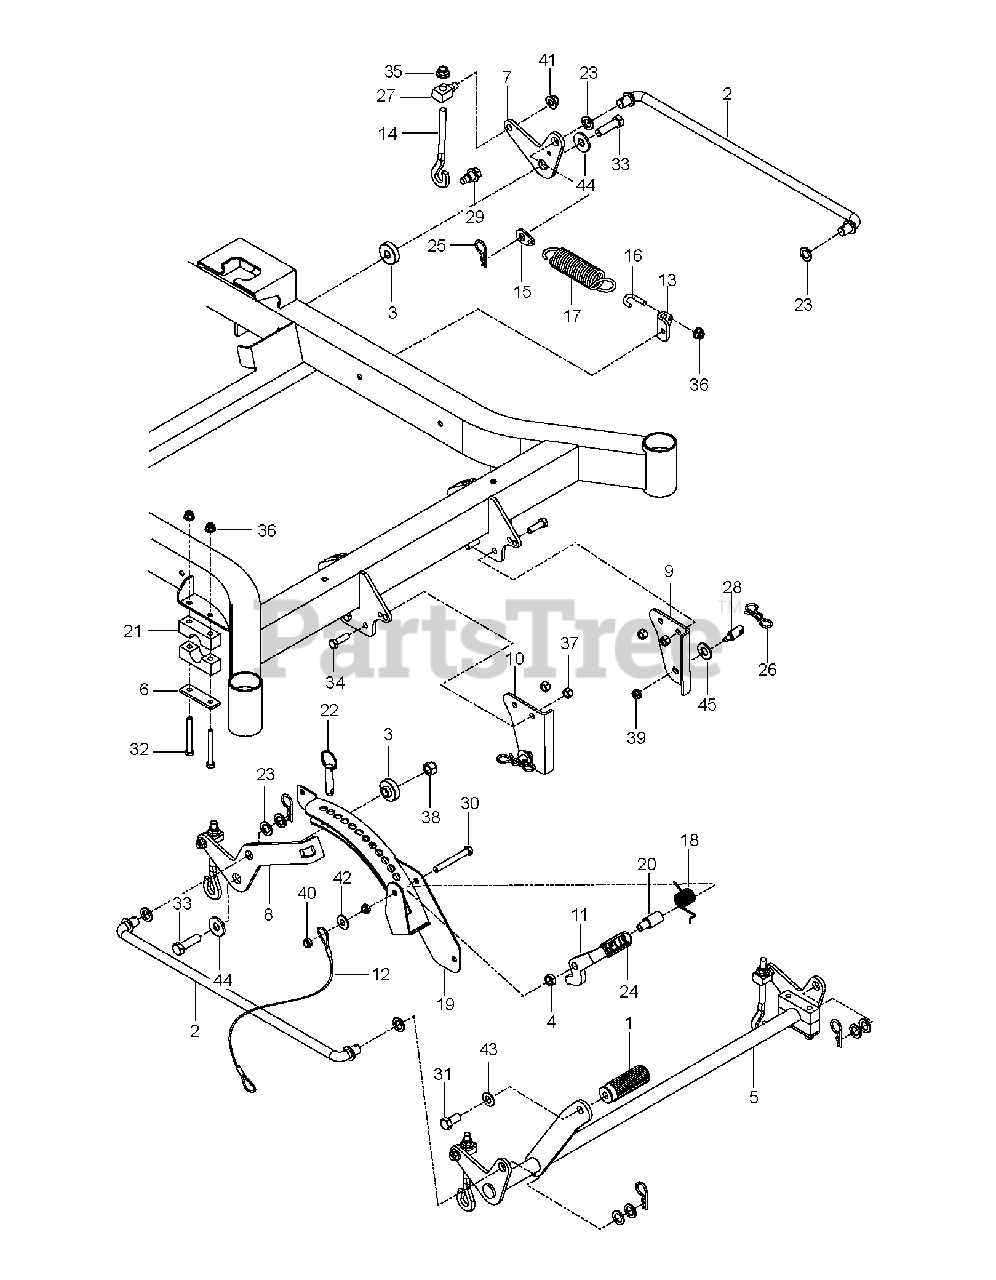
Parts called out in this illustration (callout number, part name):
1	PEDAL, DECK HEIGHT
2	CROSS LINK
3	SPACER.IDLER.METAL.POWDER
4	SPACER, .3
5	LIFT.PNT.MZ.DECK.WELD.E-DIP
6	REINFORCEMENT.PLATEX431
7	BELLCRANK, RR, LIFT
8	BELLCRANK, RR, RT
9	BRACKET.PNT.SUSP.CHAS.FR.LH.OR
10	BRACKET.PNT.SUSP.CHAS.FR.RH.OR
11	LATCH, TRANSPORT
13	MOUNT, SPRING
14	LINK.ADJUSTABLE
15	TAB, SPRING
18	SPRING, TORSION
19	HEIGHT, ADJUST, DECK
20	PIVOT, LATCH, TRANSPORT
21	PILLOW BLOCK
22	PIN, 1/2 X 1 1/2, DETENT RING
24	GRIP, TRANSPORT-RELEASE
25	PIN, COTTER 1 3/4
26	PIN.COTTER.7/16.BOW TI.
28	STUD.FASTNER.W/ANTI-ROTATE
29	BOLT.SHOULDER
30	BOLT.HEX.FIN.3/8-16 X 3.GR5
31	HHCS 1/2-13 X 1
32	HCS 5/16C X 2-3/4
33	HCS 1/2-13 X 1 3/4 GR 8
34	HCS 3/8-16X1.GRD.5.ZD
35	Flange Hex Ins Nut, Black 3/8-16
36	5/16-18 NYLOC FLANGE NUT
37	NUT 3/8-16 NYLOC
38	RP NUT 1/2-13 HEX NYLOC ZD
39	NUT LOCK HEX FLANGE 5/16-18
40	NUT HEX 3/8-16 NYLON, THIN
41	NUT LOCK FLG 3/8-16 UNC
42	WASHER 3/8 FLAT
43	WASHER, 7/16 DISC SPRING
44	WASH USS FLAT 1/2
45	WASHER.CLEAR.ZINC
